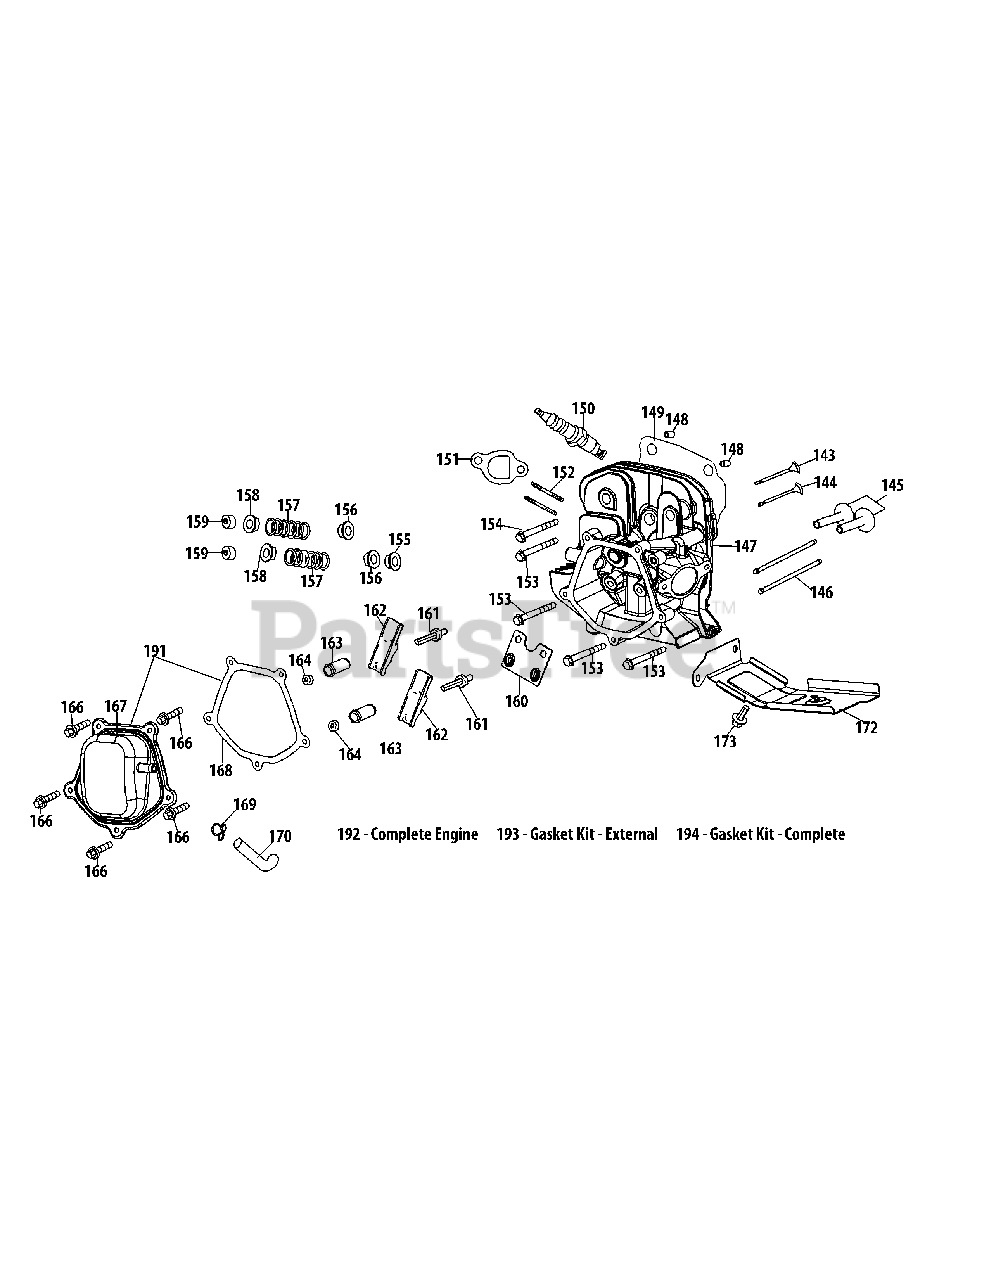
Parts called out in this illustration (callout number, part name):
143	Valve Kit
144	Valve Kit
145	Tappet
146	Push Rod Kit
147	Cylinder Head Assembly
147	Cylinder Head Kit
148	Dowel Pin 12×20
149	Gasket, Cylinder Head
150	Spark Plug/F6Rtc
151	Exhaust Pipe Gasket
152	Stud M8×48.5
152	Muffler Stud Assembly
153	Bolt M10×1.25×87
154	Bolt M10×1.25×65
155	Valve Seal (Intake)
156	Valve Spring Retainer(Intake)
157	Valve Spring
158	Valve Spring Retainer (Exhaust)
159	Exhaust Lash Cap
160	Push Rod Guide
161	Bolt, Pivot
162	Rocker Arm
163	Adjusting Nut ,Valve
164	Nut, Pivot Locking
166	Valve Cover Bolt
167	Valve Cover
168	Valve Cover Gasket
169	Breather Hose Clamp
170	Breather Hose
172	Air Shield
173	Bolt M6×12
191	Valve Cover Kit
192	Complete Engine
193	Gasket Kit - External
194	Gasket Kit - Complete
